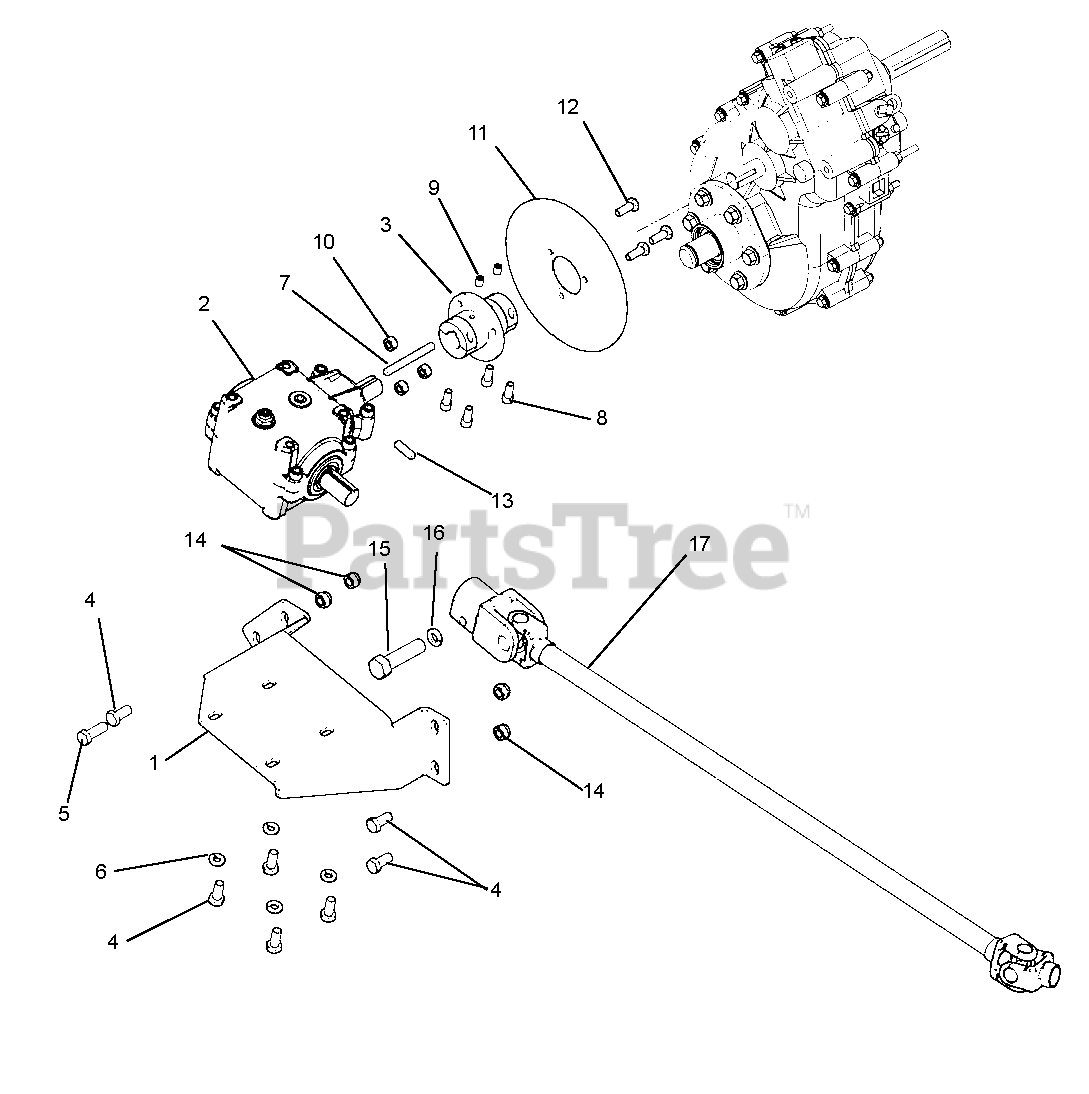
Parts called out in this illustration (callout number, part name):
1	GEAR BOX MNT PLATE
2	GBOX MODEL R100 1.5 TO 1 RATIO
3	CLAMP COUPLING
4	BOLT, HEX .31-18 .75 G5 YWZC
5	BOLT, HEX .31-18 1.00 G5 YWZC
6	WASHER, LOCK .31 X. 078 REG YWZC
7	KEY .188 X .188 X 2.50 SQ
8	HSHCS 1/4-28 X 5/8
9	SET SCREW, .25-28 X .375 ALHD CUP
10	NUT, LOCK CENTER .25-20 YWZC
11	DISK, PARK BRAKE
12	BOLT, HEX .25-20 X .75 GR5 YWZC
13	KEY, 3/16 X 7/8
14	NUT, HEX NYLOCK .312-18 YWZC
15	BOLT, HEX .38-16 X 2.0 GR5Y REG TWZCWZV
16	WASHER, LOCK .38 X .094
17	REAR HALF DRIVELINE
